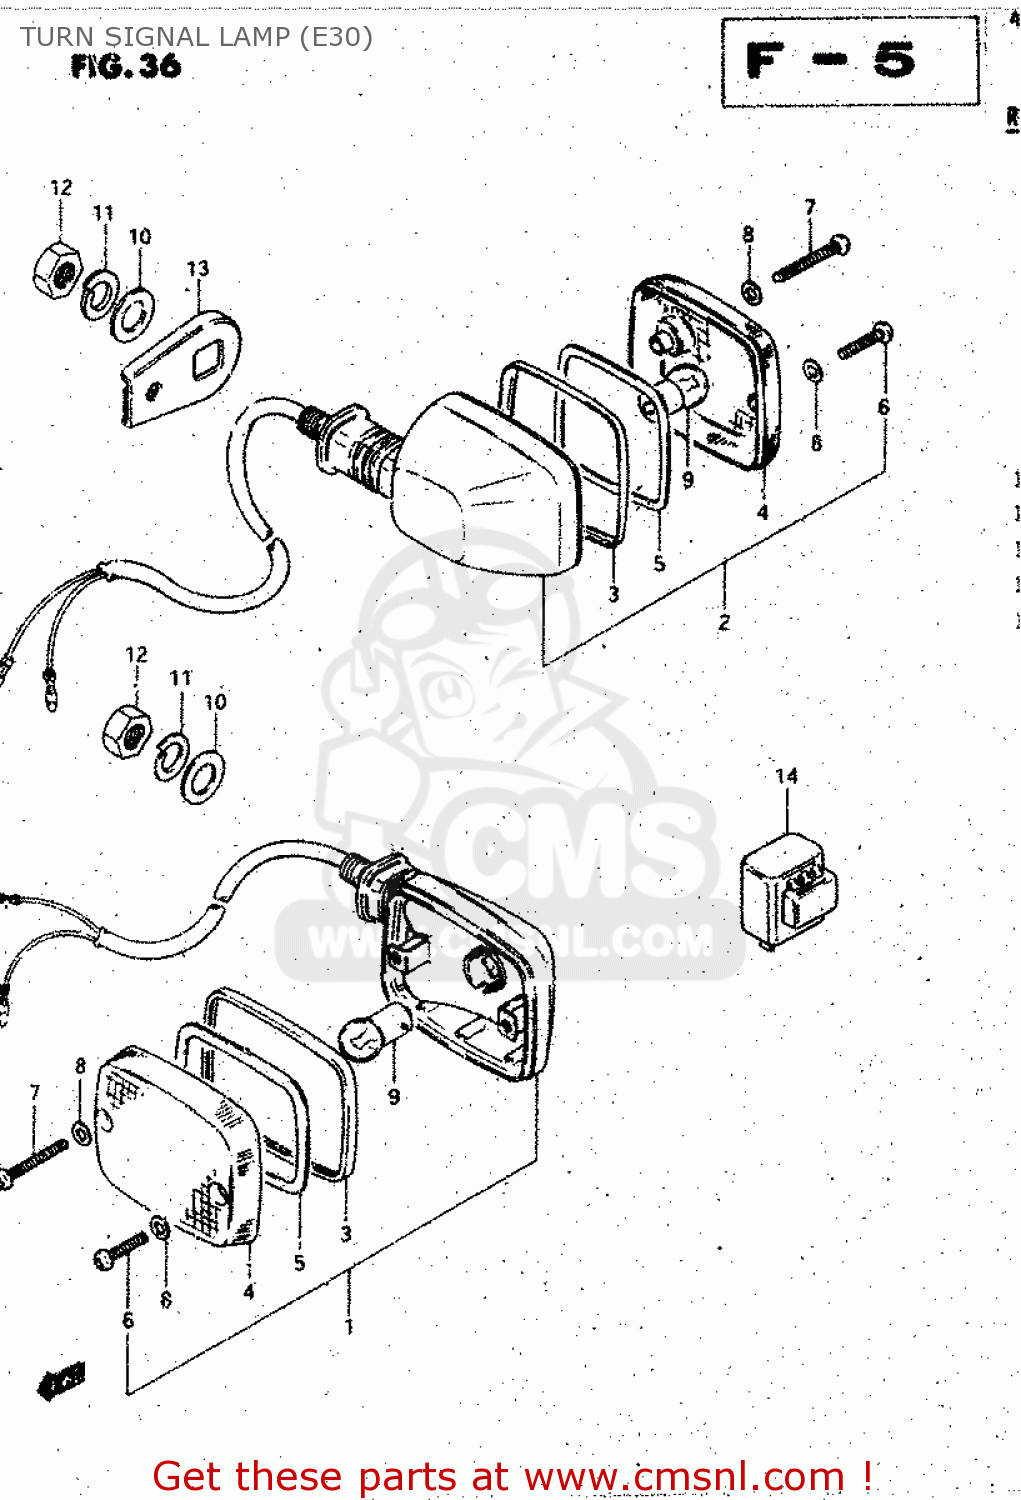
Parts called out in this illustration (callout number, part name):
1	LAMP ASSY, FRONT TURN SIGNAL
2	LAMP ASSY, REAR TURN SIGNAL
3	RIM
4	LENS
5	GASKET (NAS)
6	SCREW
7	SCREW
8	GASKET (NAS)
9	BULB 12V 10W
10	WASHER (12.5X26X1.6)
11	WASHER,LOCK 12
12	NUT
13	BRACKET, REAR
14	RELAY,TURN SIGNAL
